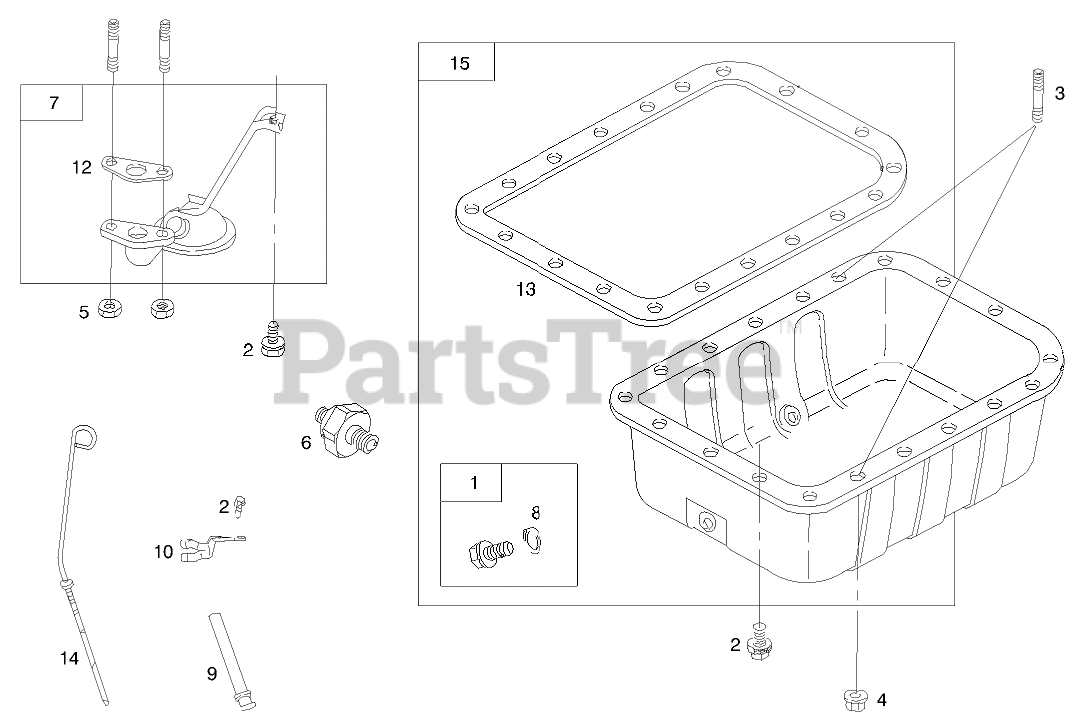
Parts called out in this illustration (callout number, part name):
1	PLUG-OIL DRAIN (12MM)
1	HEAD-CYLINDER
2	SCREW-HEX
3	STUD-METRIC
4	NUT-HEX, METRIC
5	NUT-HEX, METRIC
6	SWITCH-PRESSURE, OIL
7	SCREEN-PUMP, OIL
8	WASHER-SEAL (12MM)
8	SWITCH-TEMPERATURE, WATER
9	TUBE-DIPSTICK
9	GASKET-SET
10	BRACKET-SUPPORT
12	GASKET-STRAINER, OIL
13	GASKET-PAN, OIL
14	Dipstick
14	KIT-VALVE OVERHAUL
15	PAN-OIL
15	SHAFT-GEAR
